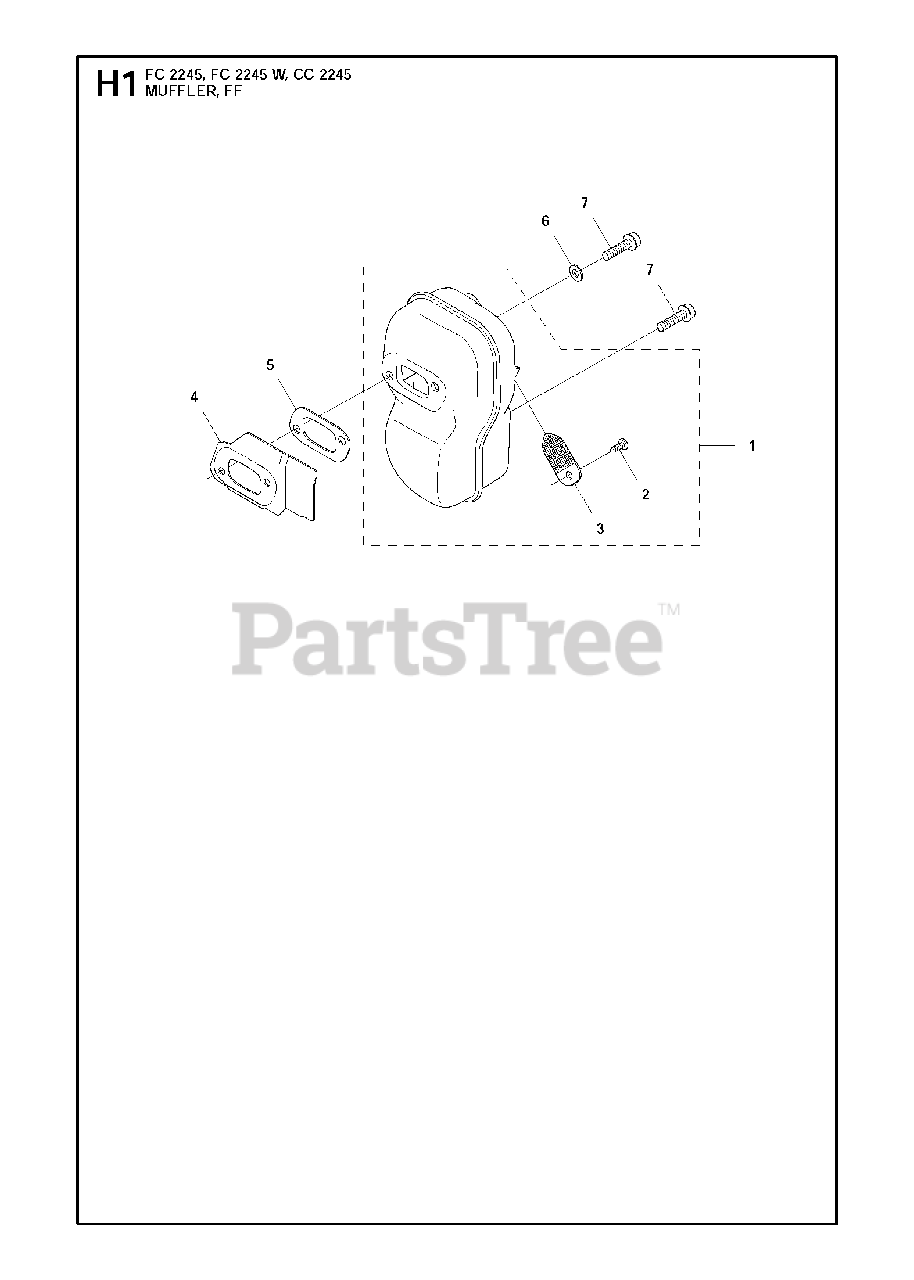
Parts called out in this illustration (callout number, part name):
1	MUFFLER ASSY
2	SCREW
3	SPARK ARRESTOR SCREEN
4	HEAT DEFLECTOR
6	DOUBLE WASHER
